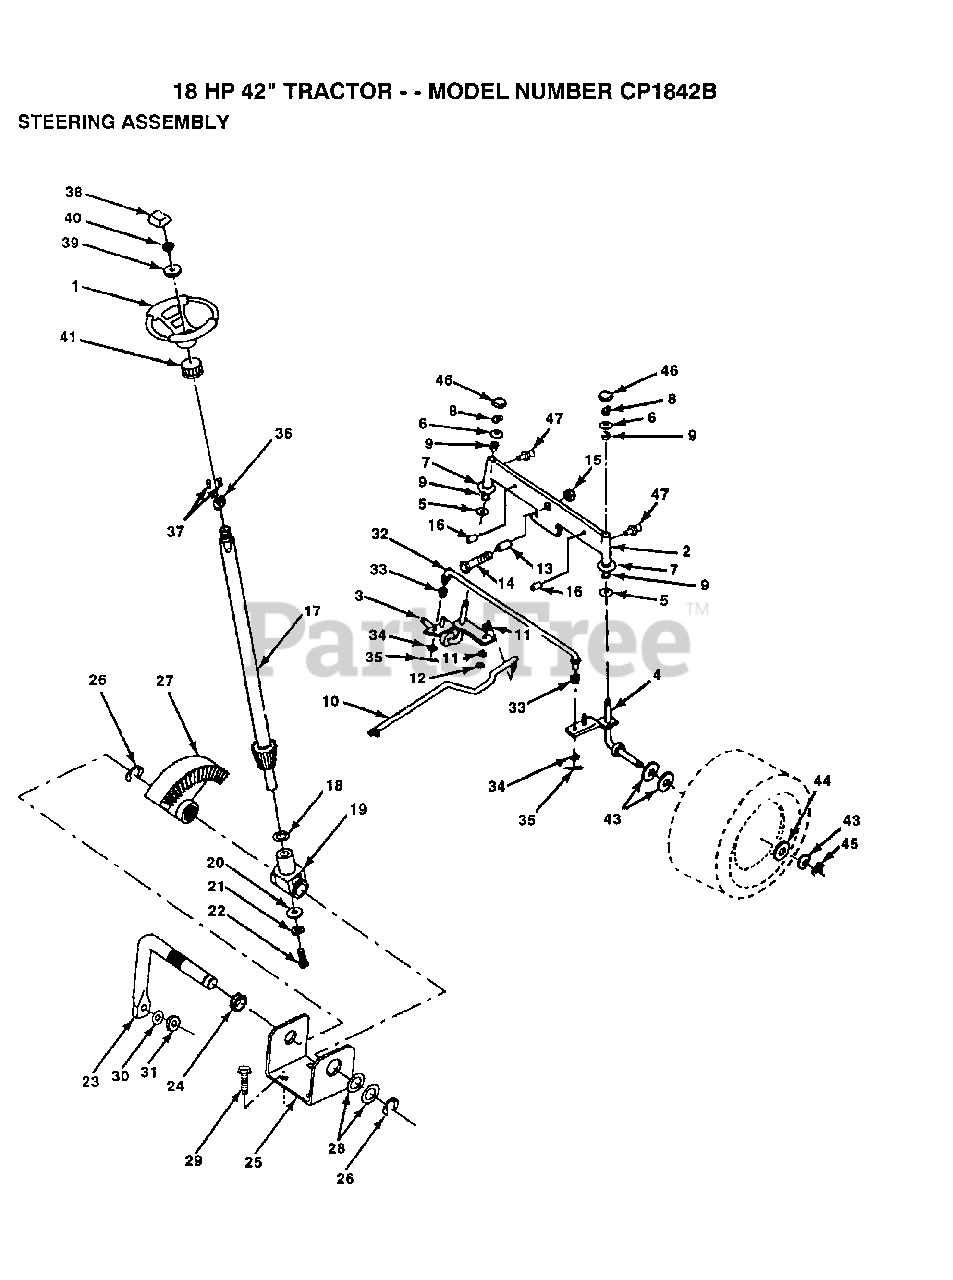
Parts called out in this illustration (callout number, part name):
3	SPINDLE LH
4	SPINDLE RH
5	WASHER .T
6	WASHER
7	WASHER
8	RING
9	COL. SRTG. BEAR.
11	LOCKWASHER
13	BEARING
14	BOLT HEX 5/8-11
16	AXLE PIN
17	STEERING SHAFT
18	THRUST WASHER
19	SUPPORT.SHAFT
21	LOCKWASHER
22	"SCREW,SPECIAL"
24	NYLINER T
25	"BRKT,STEERING"
26	RING
28	WASHER .T
29	SCREW
30	LOCKWASHER
32	TIE ROD
33	BUSHING.DRAGLINK
34	WASHER
35	COTTER PIN
38	INSERT-WHEEL LT
39	WASHER
41	ADAPTER LT
43	WASHER
44	WASHER
45	RING
46	CAP
47	ZERK M
